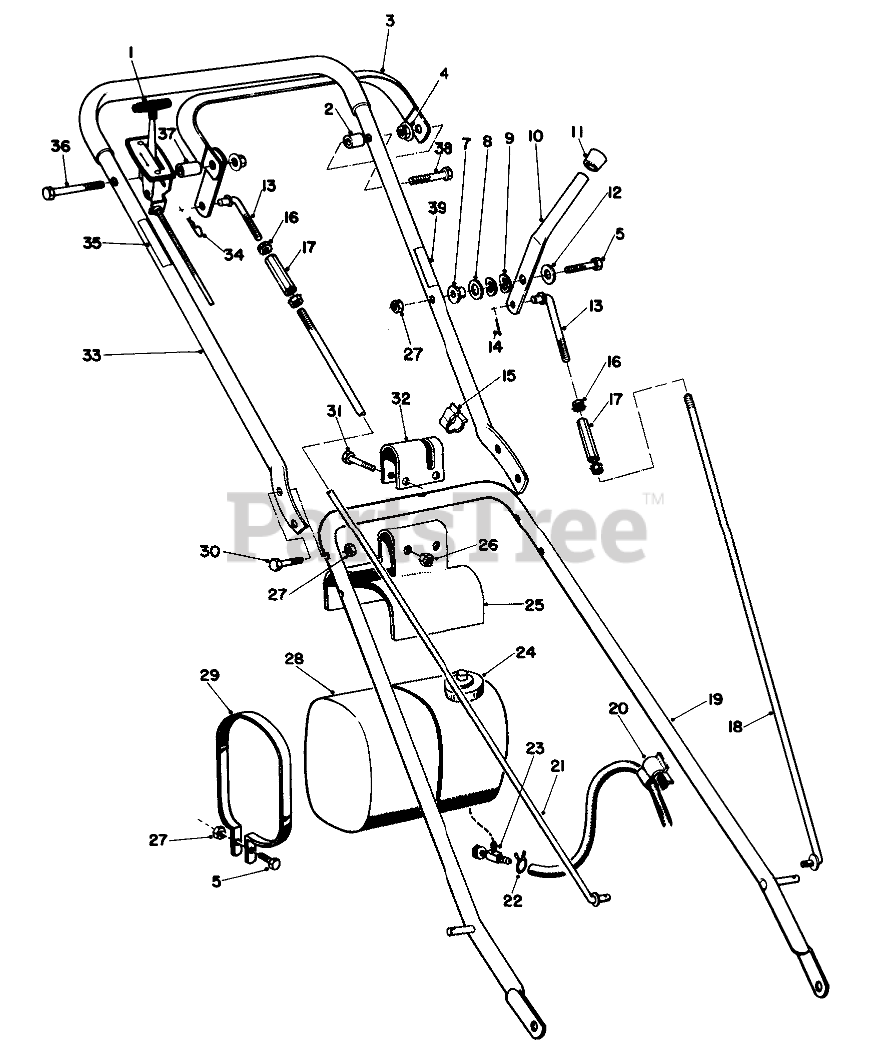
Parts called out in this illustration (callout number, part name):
1	Control, Throttle
2	Spacer
3	Control Bail
4	NUT-LOCK, HHF
5	SCREW-HH
7	PIVOT
8	WASHER-FLAT
9	WASHER-SPRING
10	CUTTER HANDLE R
11	Button Plug
12	WASHER-FLAT
13	LINK CONTROL ROD
14	PIN-COTTER
15	Clamp
16	NUT-KEPS
17	CONTROL ROD SLEEVE
18	CUTTER CONTROL ROD
19	LOWER HANDLE WA
20	CLAMP
21	CONTROL ROD
22	Clamp
23	.125 ID SHUTOFF VALVE
25	FUEL TANK BRACKET
26	Nut
27	NUT-LOCK
28	Tank
29	TANK STRAP
30	SCREW-HH
31	SCREW-HH
32	Clamp
33	Upper Handle
34	PIN-COTTER
35	Decal-Throttle
36	SCREW-HH
37	SLEEVE-PIVOT ROLLED
38	SCREW-HH
39	BLADE CONTROL DECAL
